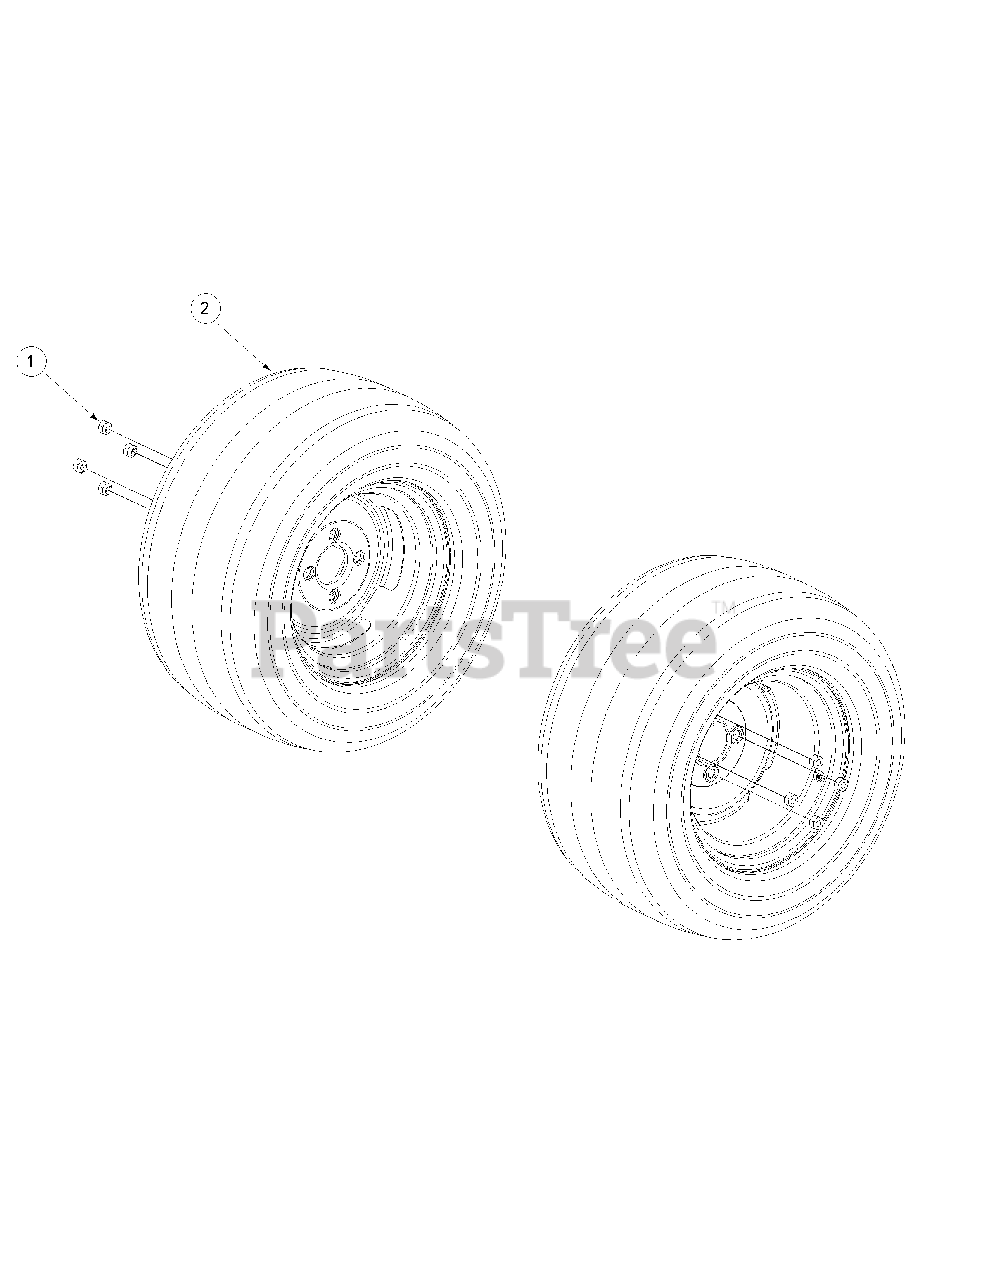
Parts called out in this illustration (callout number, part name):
1	Lug Nut, 1/2-20
2	Wheel Assembly, 23 x 9.5-12, Turf Pro, Includes:
2	Tire, 23 x 9.50-12, Turf Pro Rim, 12 Dia x 7.00 width
